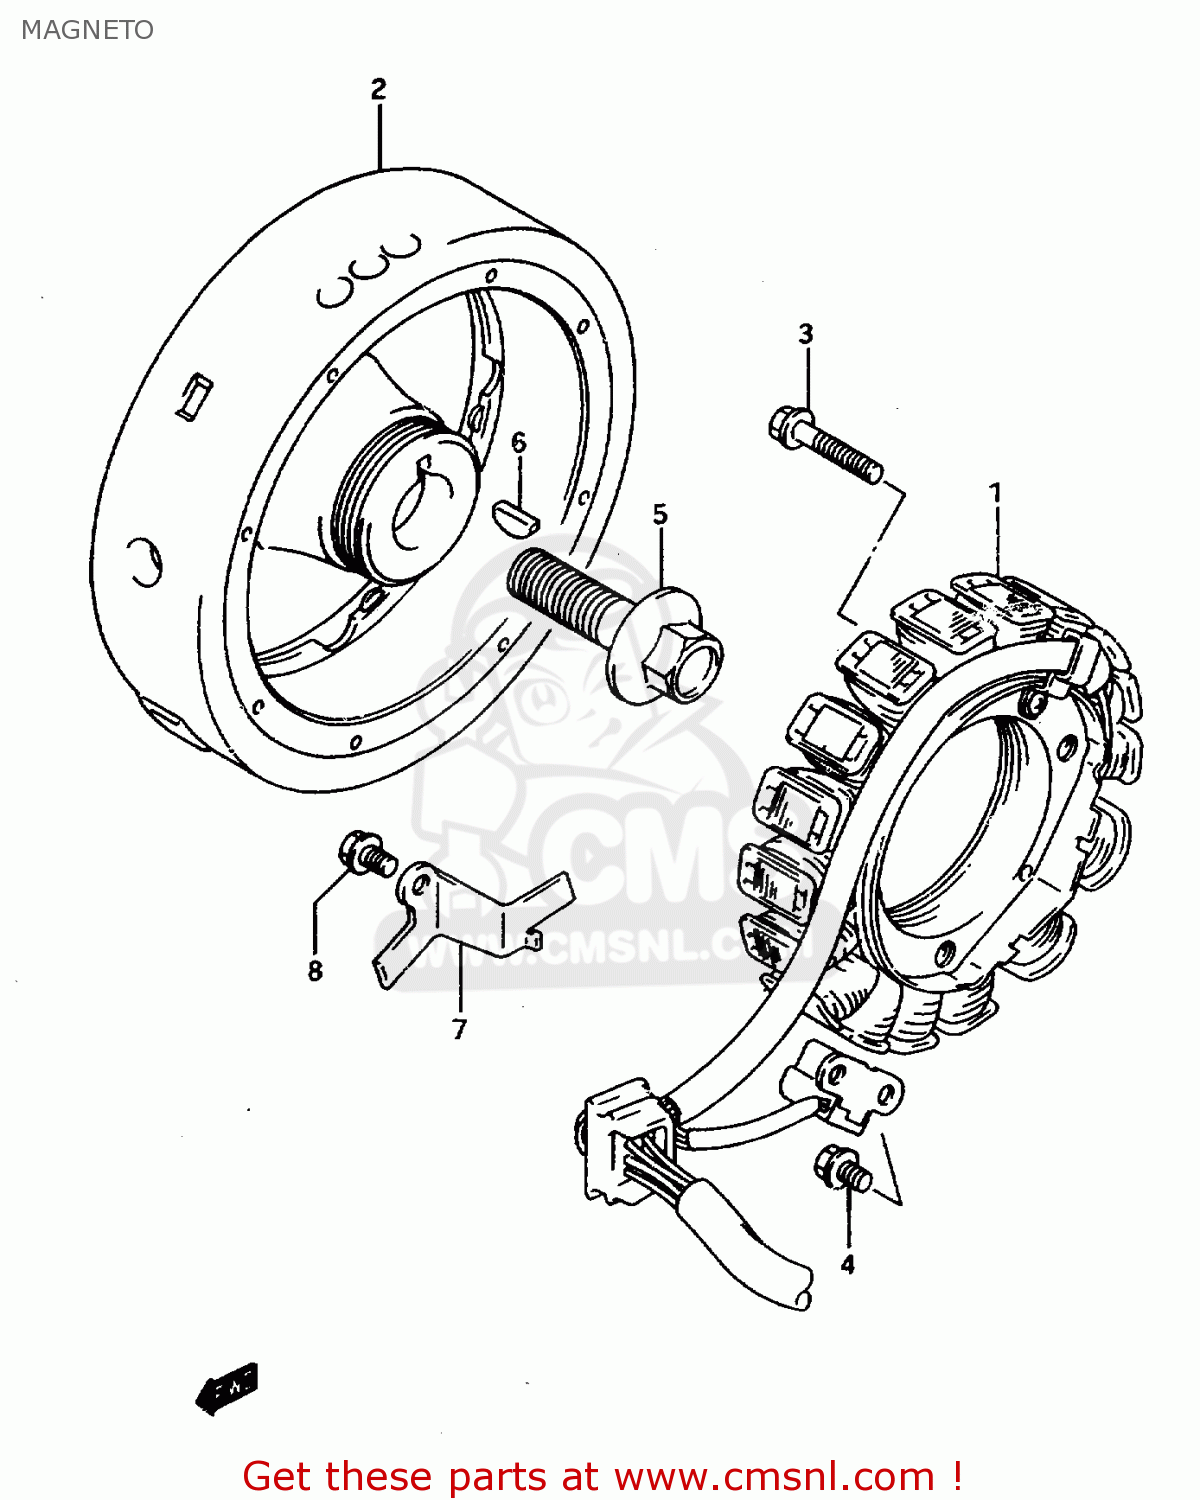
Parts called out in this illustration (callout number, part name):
1	STARTER ASSY
2	ROTOR
3	BOLT
4	BOLT
5	BOLT(14X43)
6	KEY
7	CLAMP,MAGNETO LEAD WIRE
8	BOLT
